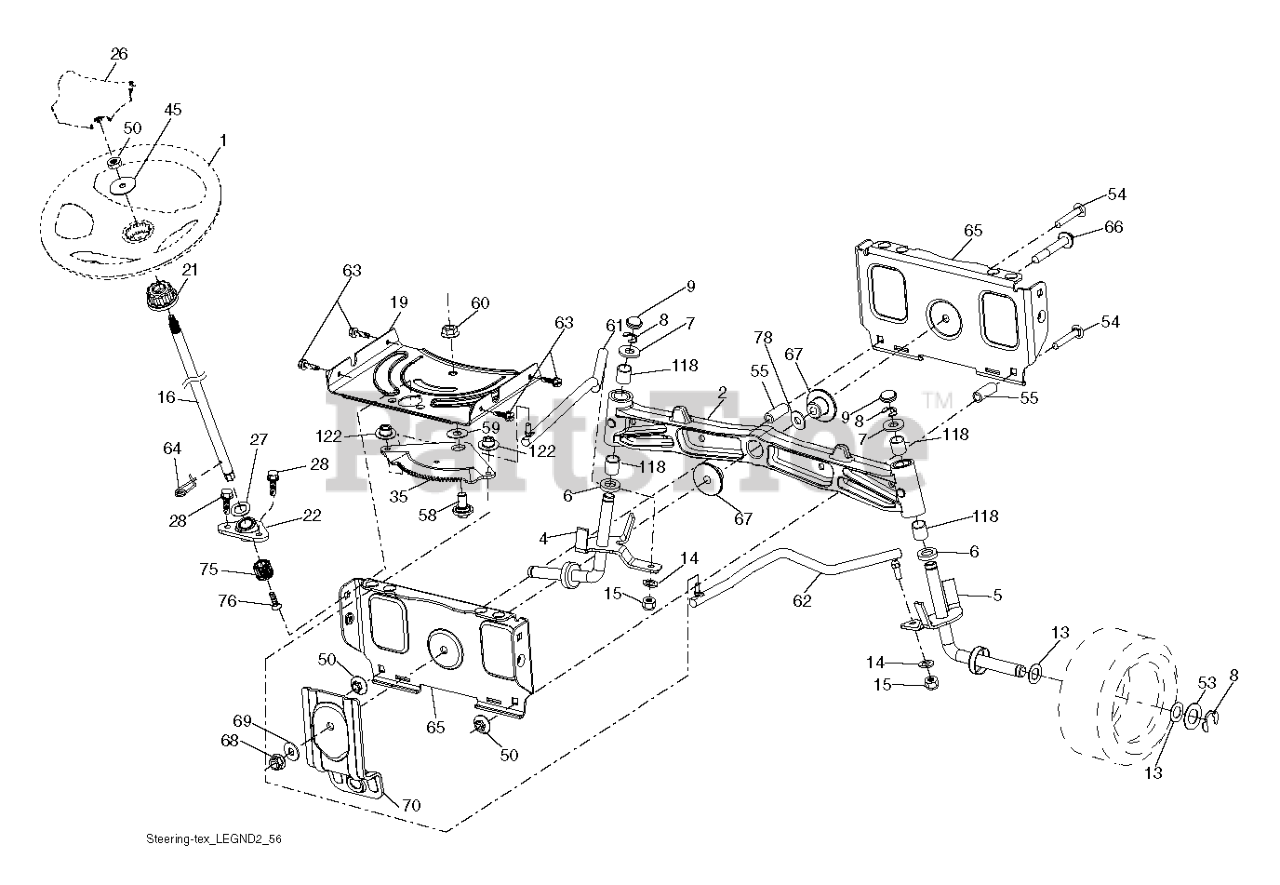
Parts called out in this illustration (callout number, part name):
1	WHEEL.STEER.HUSQ.SR.498.OVMLD
2	AXLE.SVC.ASM CAST IRON.TEX
4	SPINDLE.WELDED.LH.16"TEX
5	SPINDLE.WELDED.RH.16"TEX
6	THRUST WASHER
9	CAP.SPINDLE.BLACK
14	WASHER, LOCK 3/8
15	NUT CROWNLOCK 3/8-24
16	SHAFT.STEER.STEALTH.DD
19	PLATE.STEER.DDL.NLT/NG
21	ADAPTER, WHEEL STNG..
22	STEERING.SUPT.LOWER.
26	INSERT.CAP.WHL.STRG.HUSQ.PREM
28	SCREW, 3/8-16X3/4
35	GEAR.SECTOR.PLATE.DDL.
45	WASHER 9/16"ID, 2 3/8"OD
50	NUT LOCK FLG 3/8-16 UNC
51	NUT.HEX.1/2-20
53	WASHER.HARDENED
55	SPACER.BRACE.AXLE
58	BOLT.SHOULDER.SECTOR.P
59	WASHER.THURST.SECTOR.S
60	NUT FLANGE LOCK 5/8-11
61	DRAGLINK.LH.BALLSTUD.D
62	DRAGLINK.RH.BALLSTUD.D
63	SCREW
64	RETAINER.CLIP.SPRING.S
65	BRACE.AXLE.FRONT.NLT/N
66	BOLT HEX FGHD 7/16-14 X 3 SERR
67	BUSHING.PM.FRONT AXLE
68	NUT.LOCK.FLANGE.7/16
69	WASHER.1.5X.505X.118
70	BRACKET.FRT.DECK.SUSP.RR.MT431
78	THRUST WASHER
118	BUSHING, AXLE CAST
122	CAP.GEAR.SECTOR.TEX
